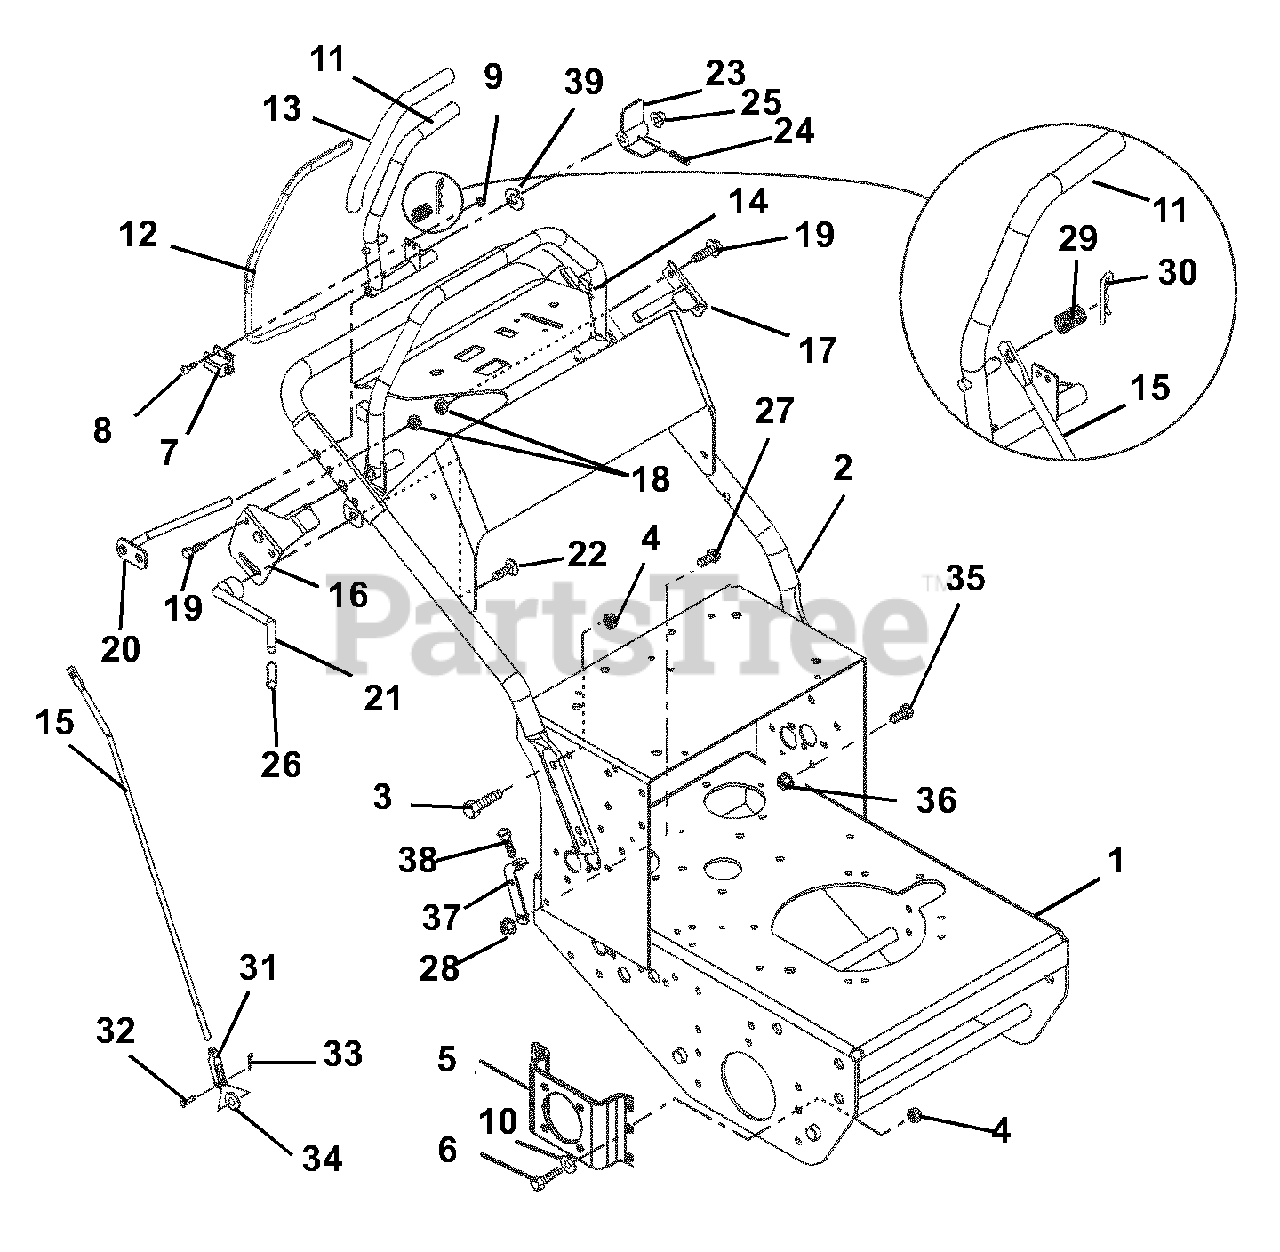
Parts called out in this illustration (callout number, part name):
1	Kit, Frame with Decals
2	Kit, Handlebar with Decals HR15-Pro Steer
3	Bolt, Hex .38-16 x 1.00 Grade 5
4	Nut, Locking Nylon .38-16
5	Bracket, Wheel Motor Left Hand
5	Bracket, Wheel Motor Right Hand
6	Bolt, Hex .38-16 x 1.00 Grade 5
7	Switch, Double Pole
8	Screw, Machine 10-24 x .75 Hex Washer Head
9	Nut, Locking Nylon 10-24 with Insert
10	Washer, Flat Steel .406 x .812 x .065
11	Weldment, Lever-Right Hand Speed Control
11	Weldment, Lever-Left Hand Speed Control
12	Lever, Operator Presence
13	Grip, Handlebar
14	Weldment, Speed Control Stop (Serial # 101-2999)
14	Weldment, Speed Control Stop (Serial # 3000 and up)
15	Rod, Steering
16	Weldment, Control Stop Limiter-Right Hand (Serial # 101-2999)
16	Weldment, Control Stop Limiter-Right Hand (Serial # 3000 and up)
17	Weldment, Control Stop Limiter-Left Hand
18	Nut, Locking Top Flange .31-18
19	Bolt, Hex .31-18 x 1.75 Grade 5
20	Weldment, Speed Control Pivot- Right Hand
20	Weldment, Speed Control Pivot- Left Hand
21	Lever, Control Stop Lock (Serial # 101-2999)
21	Lever, Control Stop Lock (Serial # 3000 and up)
22	Bolt, Round Head Square Neck .31-18 x .75 Grade 2 (Serial # 101-2999)
22	Bolt, Round Head Square Neck .38-16 x .75 Grade 5 (Serial # 3000 and up)
23	Actuator, Switch
24	Pin, Roll .125 x .75
25	Nut, Push .312
26	Grip, Hand Clutch Lever
27	Bolt, Hex .38-16 x .75 Grade 5
28	Nut, Locking Flange .375-16
29	Spring, Compression .045 x .60 x .75
30	Pin, Hair Internal .08 x .18 x 1.18
31	Yoke, .312-24 x 2.25
32	Pin, Clevis .31 x .937
33	Pin, Hair, Endries
34	Washer, Flat Steel .38 x .87 x .179
35	Bolt, Hex .31-18 x 1.00 Grade 5
36	Nut, Spin Lock Flange .312-18
37	Weldment, Reverse Adjustment Bracket
38	Bolt, Hex .31-18 x 1.25 Grade 5
39	Washer, Wave
